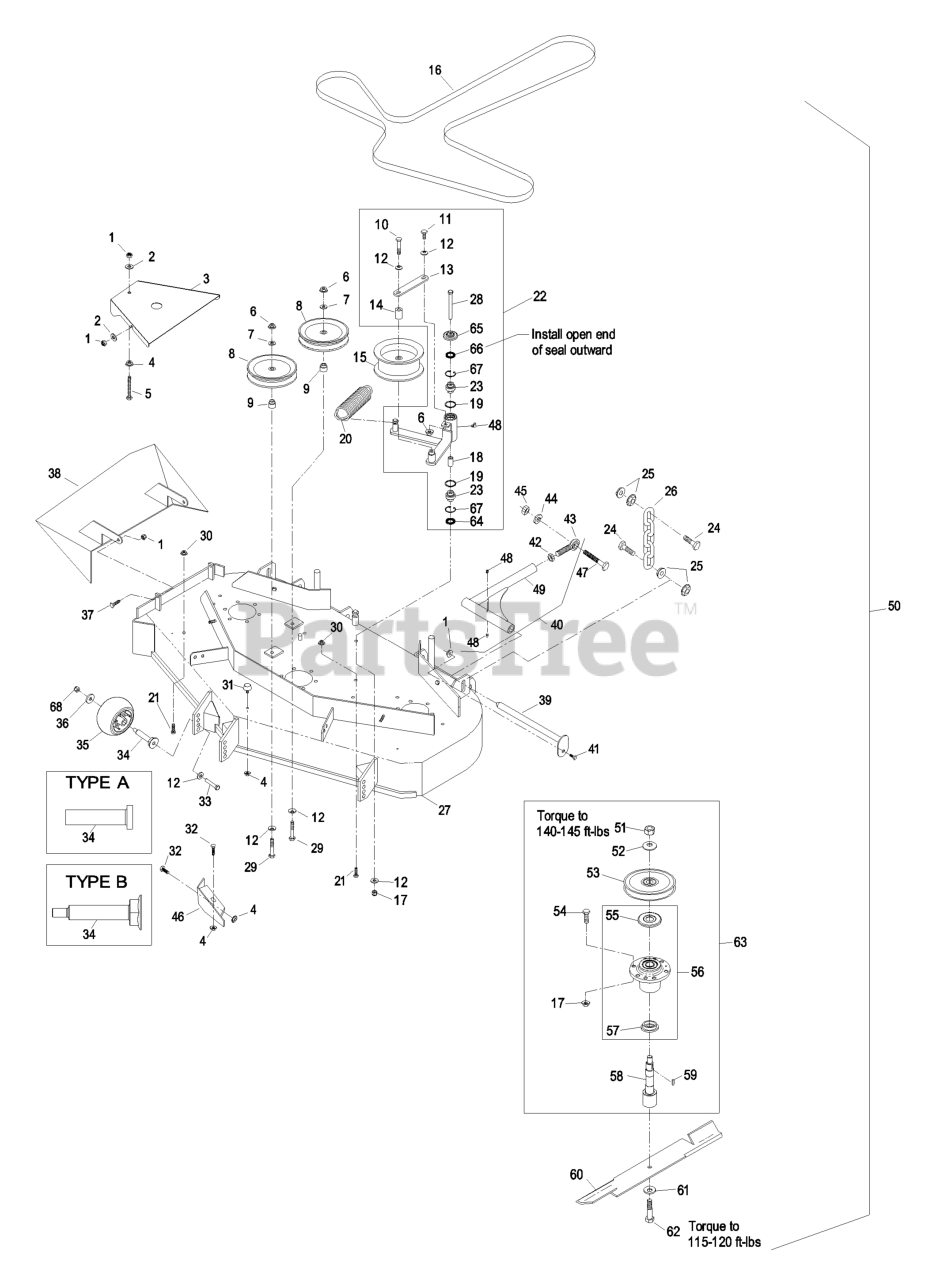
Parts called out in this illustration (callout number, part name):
1	NUT-LOCK, NI
2	WASHER-FLAT
3	SHIELD,BELT
5	BOLT,TAP HH
6	NUT-HHF, WHIZ
7	WASHER-FLAT
8	PULLEY-IDLER
9	BUSHING-IDLER
10	SCREW-HH
11	SCREW-HH
12	WASHER-BELLEVILLE
13	PLATE,GUIDE BELT (PLTD)
16	BELT,DECK DRIVE
17	NUT-LOCK, NI
21	SCREW-HH
22	KIT,DECK IDLER LHP/LCT
23	BEARING-SPHERICAL
24	SCREW-HH
26	CHAIN-LIFT, DECK
27	ASM,DECK W/DECALS LHP48 S
28	SCREW-HH
29	SCREW-HH
31	BUMPER-RUBBER
32	SCREW-HH
33	SCREW-HH
34	BUSHING-ROLLER
35	ROLLER-SCALP, ANTI
37	SCREW-HH
38	WLD,CHUTE 48
39	PIN-STRUT
40	STRUT ASM
41	SCREW-HH
42	NUT-HEX
43	BALLJOINT-SPHERICAL
44	WASHER-LOCK
45	NUT-HEX
48	FITTING-GREASE
50	Deck Complete Service (44")
51	NUT-HH
53	SHEAVE,W/HUB
54	SCREW-HH
55	GUARD-BEARING, TOP
56	KIT, CUTTER HOUSING
57	SPACER-GUARD, BOTTOM
58	SPINDLE,LHP
59	KEY-RECTANGLE
61	WASHER-BLADE BOLT, HEAVY
62	SCREW-CAP
63	ASM, CUTTER HSG 44
64	SEAL-LIP, DOUBLE
65	GUARD-TOP
66	SEAL-LIP, SINGLE
67	RING-SNAP
68	NUT-HHF, WHIZ
